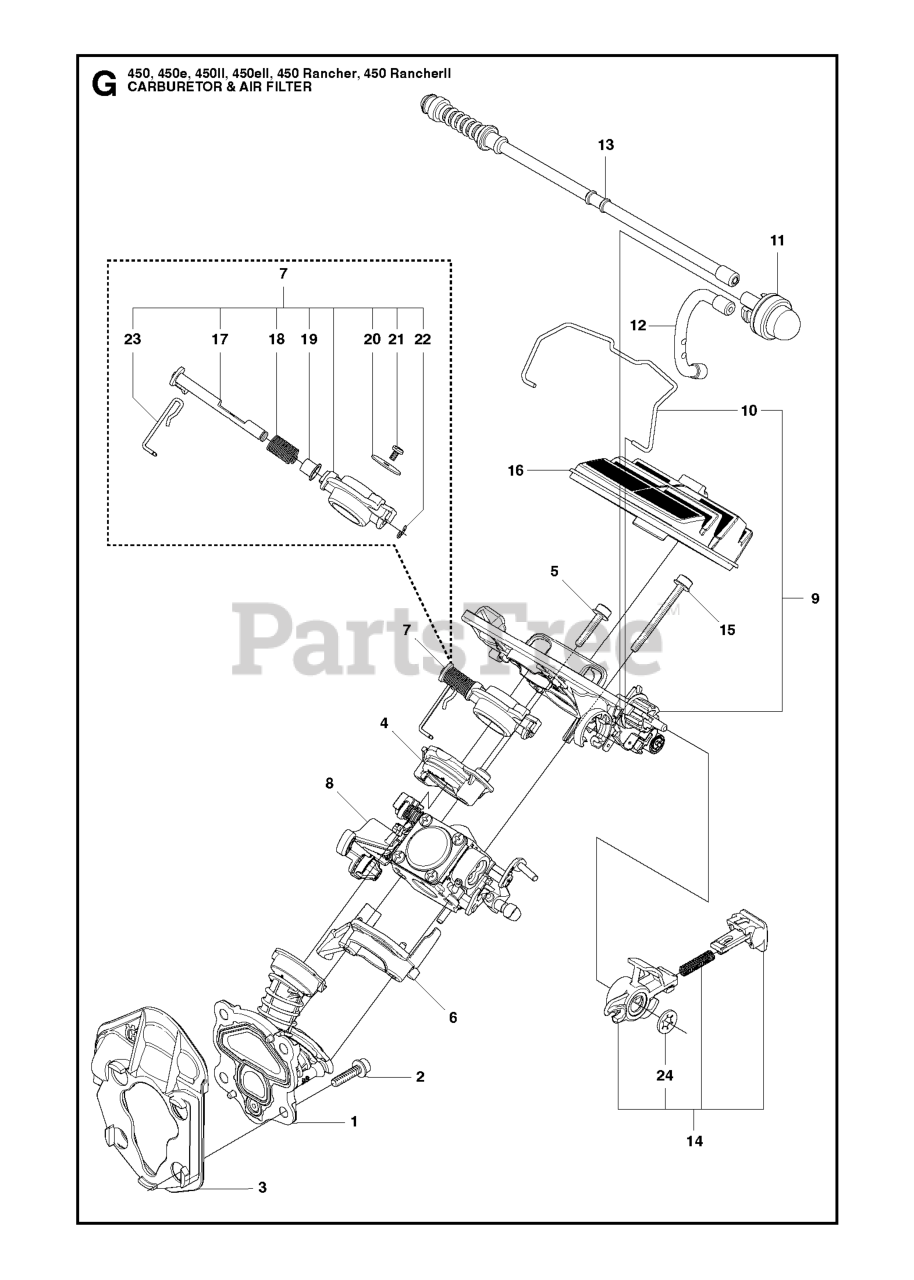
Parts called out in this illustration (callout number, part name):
1	INLET PIPE ASSY
3	INTERMEDIATE WALL
8	CARBURETOR
9	FILTER HOLDER ASSY
11	AIR PURGE BUBBLE
12	HOSE
13	RETURN HOSE
16	AIR FILTER - NYLON (80)
16	AIR FILTER - FELT
16	AIR FILTER - NYLON (44)
17	SHAFT ASSY
24	LOCK WASHER
